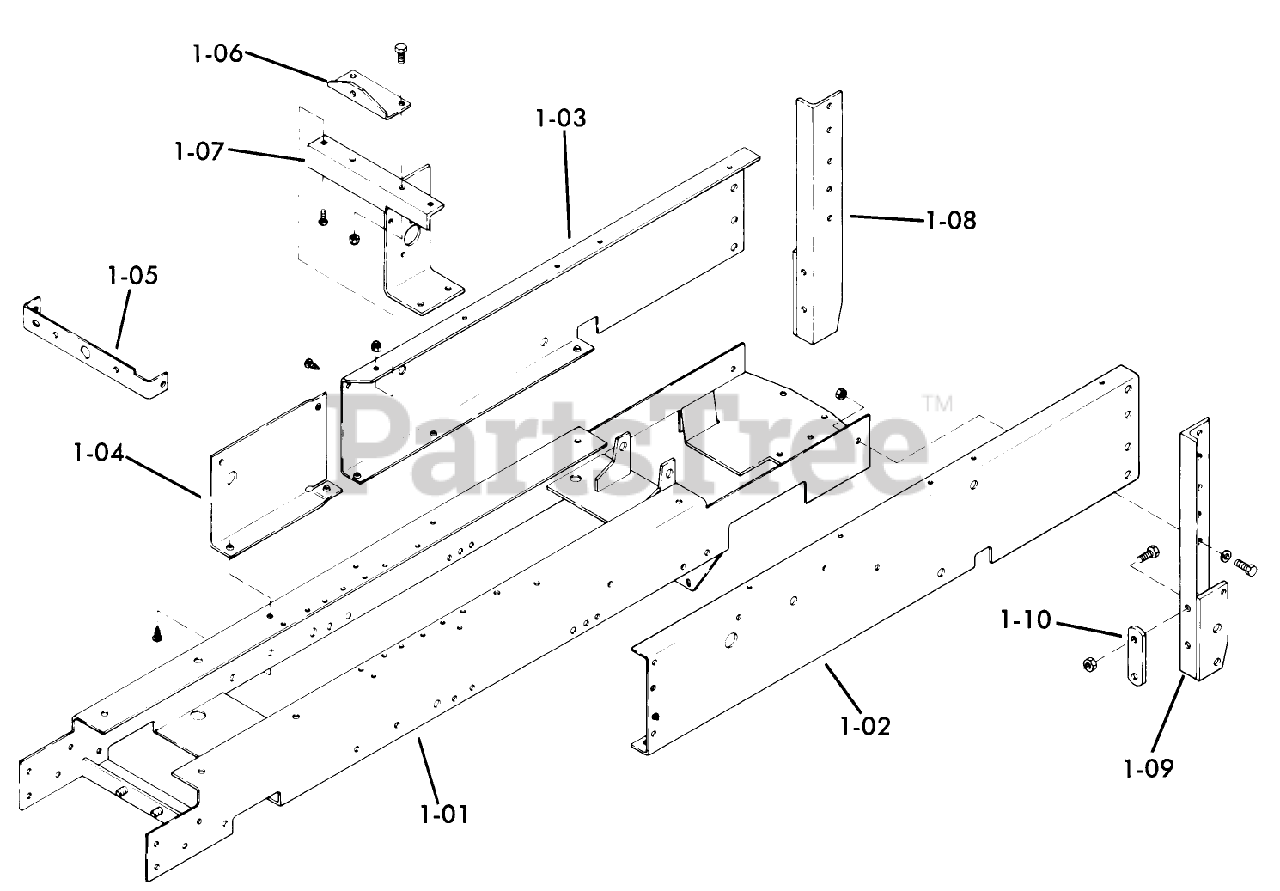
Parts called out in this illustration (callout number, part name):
1-01	Assy-Frame
1-02	Side Panel, L.H.
1-03	Hex Nut
1-04	Access Plate
1-05	Pump Mounting Plate
1-06	Pump Hanger Bracket
1-07	Steering Gear Support
1-08	Assy-Angle RH
1-09	Assy-Angle LH
1-10	BRACKET-REAR LINK MOUNTING
